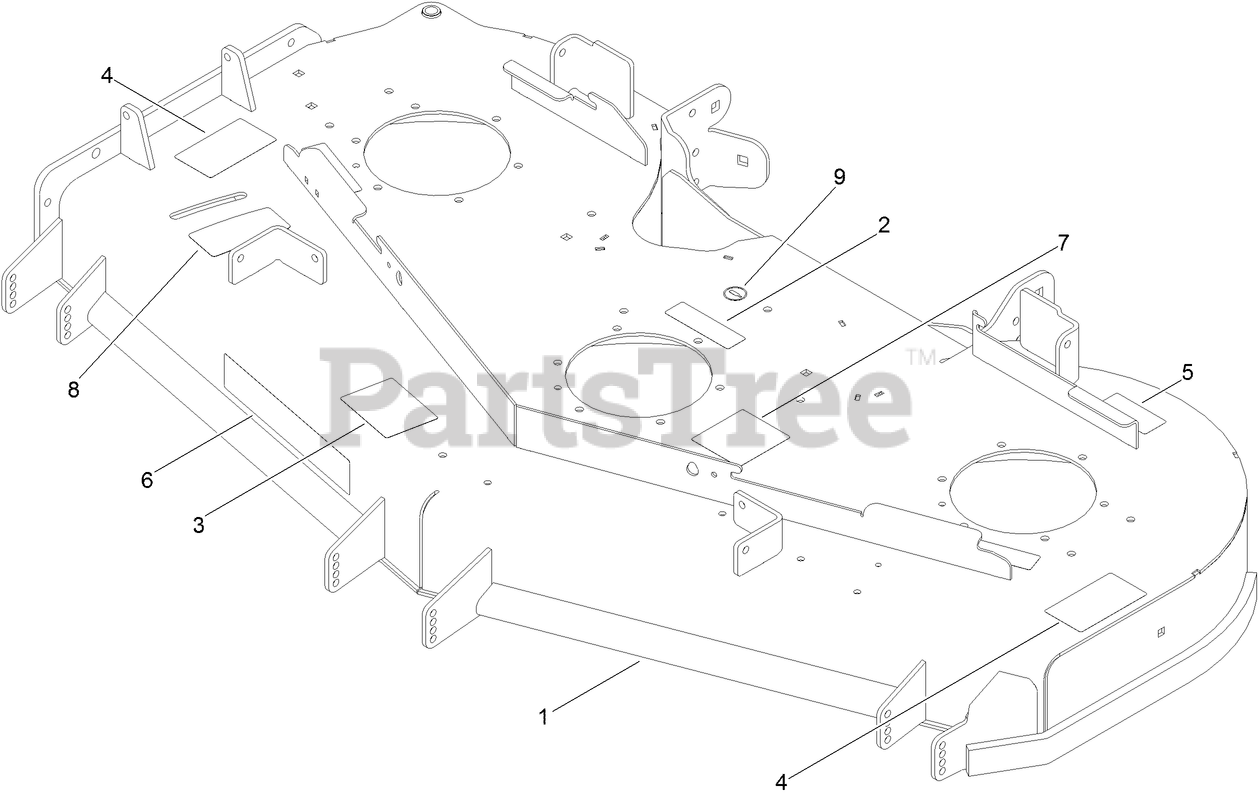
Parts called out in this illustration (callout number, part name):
1	DECK ASM
2	DECAL-COVER, MISSING
3	DECAL-SCALP, ANTI
4	DECAL-DANGER
5	DECAL-BOLT TORQUE
7	DECAL-ROUTING, DECK BELT
8	DECAL-ADJUSTMENT, BAFFLE
9	DECAL-GREASE
